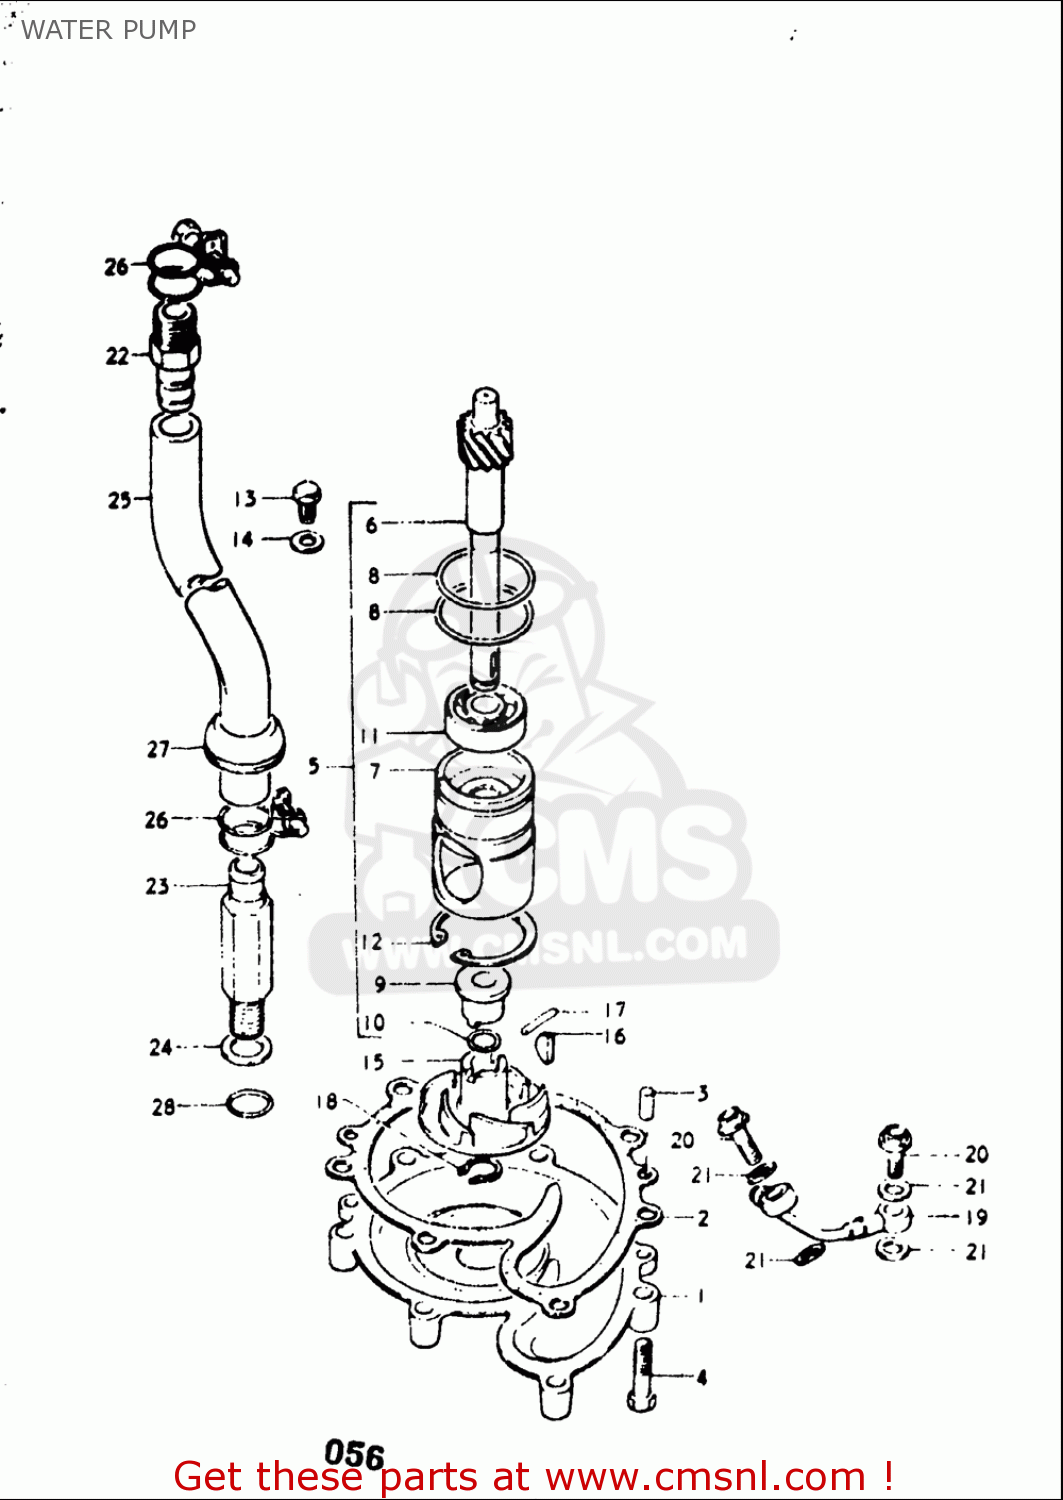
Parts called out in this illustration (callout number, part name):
2	GASKET,WATER PUMP CASE (NAS)
3	PIN
4	BOLT
5	PUMP SET,WATER
7	HOLDER,WATER PUMP DRIVEN SHAFT
8	O RING(D:1.9,ID:32.7)
9	SHEET,WATER PUMP SEALING
10	O RING(D:1.3,ID:9.6)
11	BEARING
12	CIRCLIP
13	BOLT
14	WASHER
16	KEY
17	PIN,SPRING(3X16)
18	CIRCLIP
20	UNION BOLT
21	GASKET(6.2X11X1).2 (NAS)
24	GASKET(14X19.2X2) (NAS)
25	HOSE(13X20)
26	CLAMP
28	O RING(D:2.4,ID:11.8)
